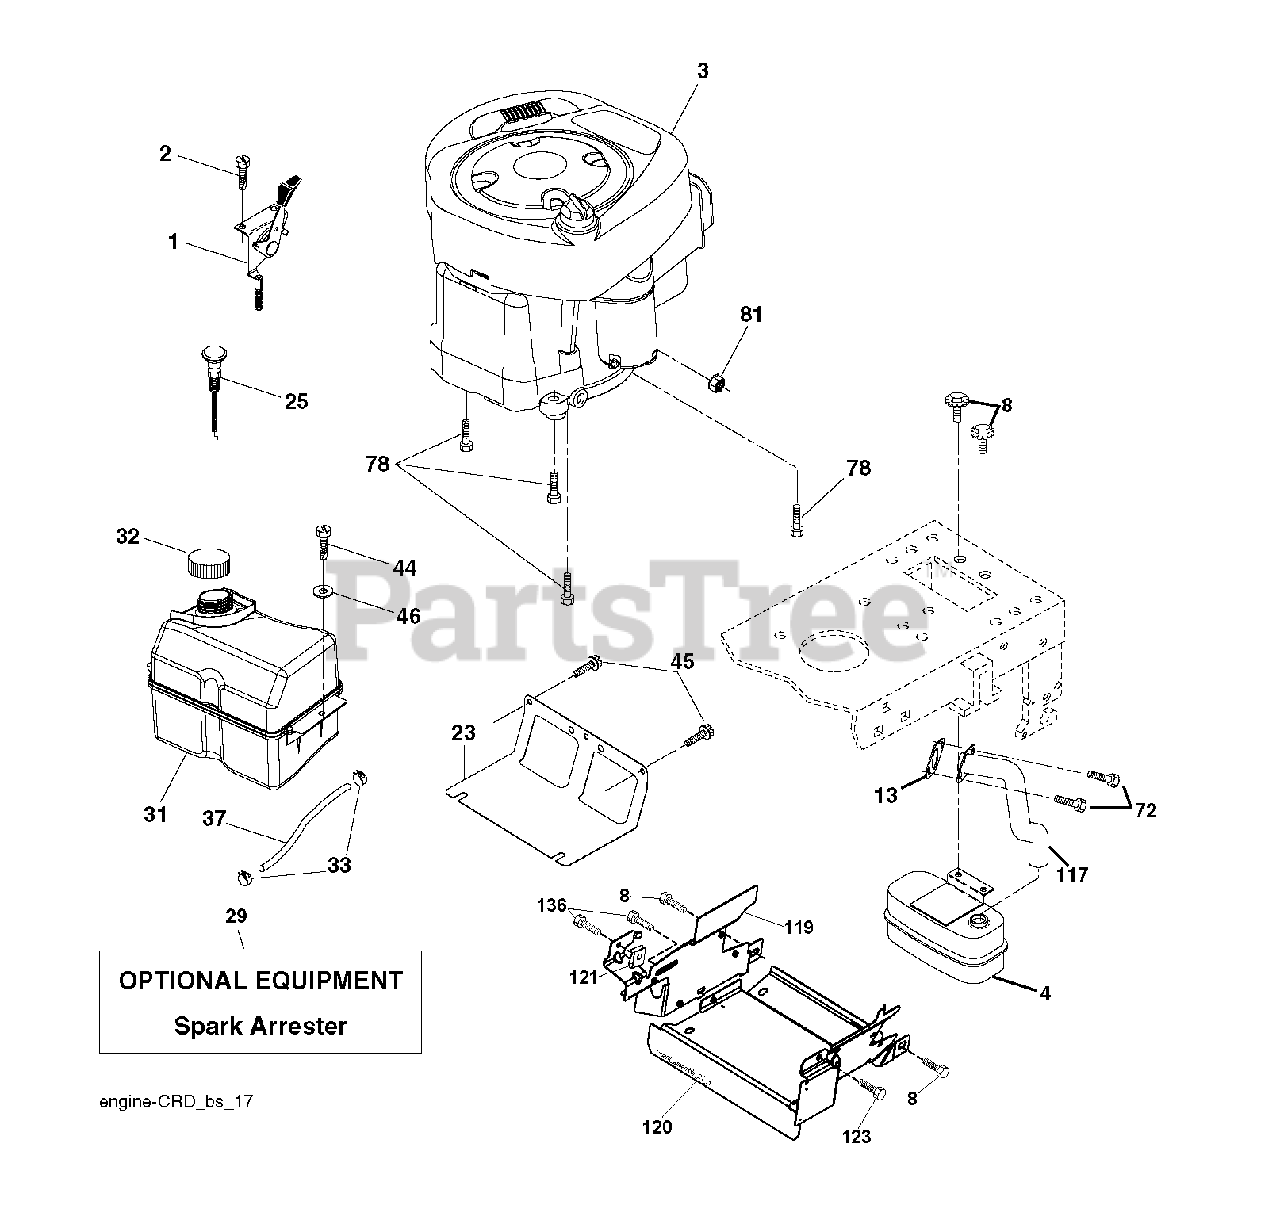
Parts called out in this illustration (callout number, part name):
1	CONTROL TH/CH FLAG
2	SCREW
4	MUFFLER.SINGLE.CYL.KOHL/B&S
8	BOLT, 5/16-18 X 1 3/4
13	REPL BY 532 27 22-93
23	SHEILD.BROWNING.DBR.GUARD
29	ARRESTER SPARK (OPTIONAL)
32	CAP ASM.FUEL.2.25"FR.
33	HOSE CLAMP
37	LINE.FUEL.20
44	SCREW HEXWSHR 1/4-20X3/4
45	SCREW, 3/8-16X3/4
72	SCREW.SOCKET HD.5/16-1
78	SCREW.3/8-16
81	NUT
117	EXHAUST.TUBE.B&S.
123	SCREW, 5/16-18 X 1/2
136	SCREW.1/4-20X5/8
